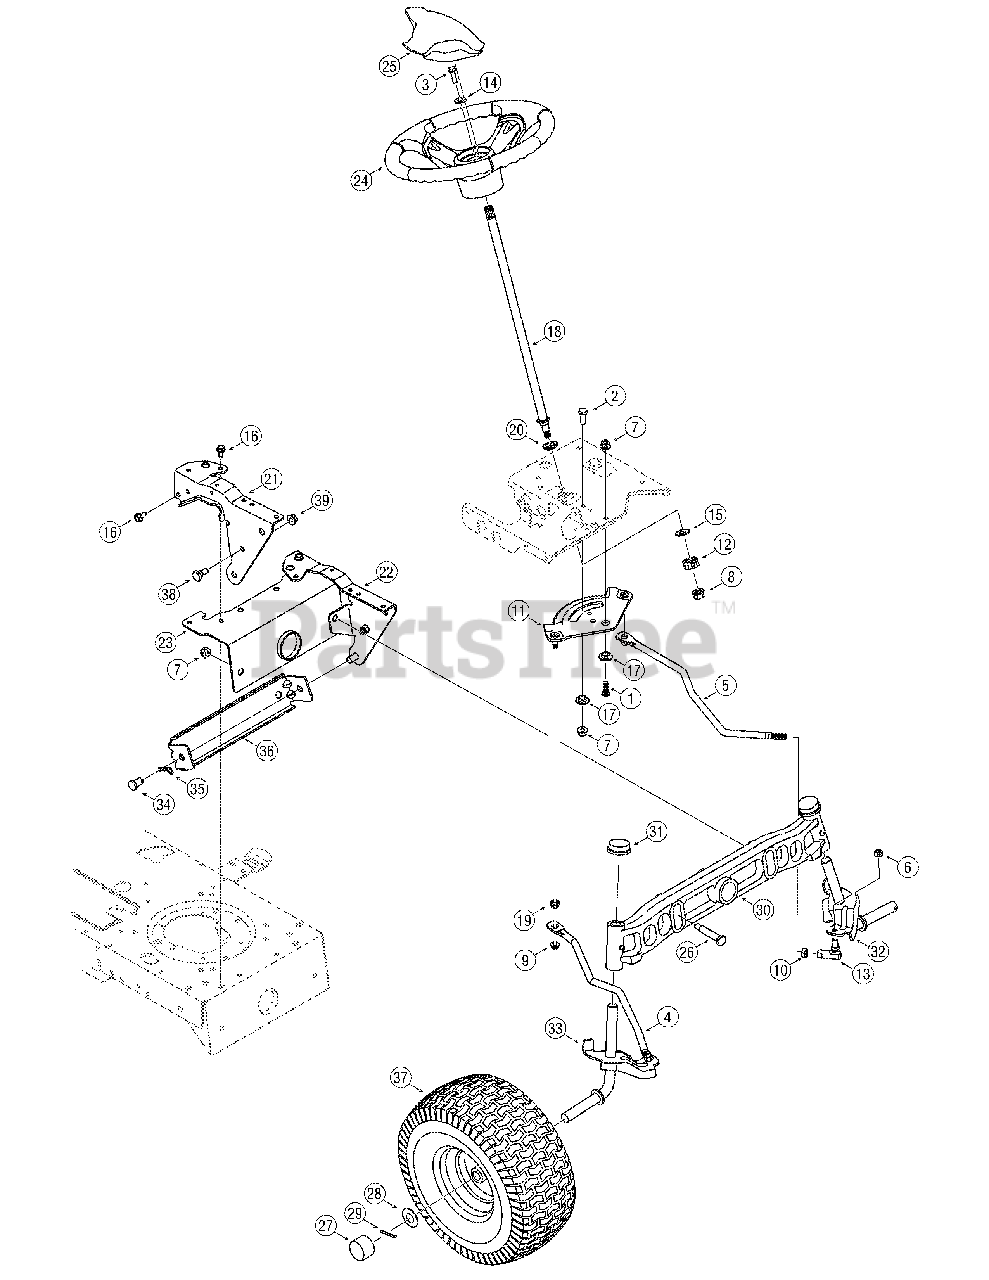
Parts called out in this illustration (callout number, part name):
1	Hex Screw, 3/8-16, 1.00, Gr5
2	Hex Screw, 3/8-16, 1.00, Gr5
3	Hex Screw, 5/16-18, 1.00, Gr5
4	Link, Drag, RH
5	Link, Drag, LH
6	Nut, Hex Lock, 3/8-24
7	Nut, Flange Lock, 3/8-16
8	Nut, Flange Lock, 7/16-20
9	Nut, Flange Lock, 5/16-18, Gr5
10	Nut, Jam, 7/16-20, Gr2
11	Gear, Steering, 11/90 Ratio
12	Gear, Pinion, Steering
13	Ball Joint, 7/16-20, Lock
14	Washer, Flat,.406 x.875 x.105
15	Washer, Flat,.51 x 1.12 x.06
16	Screw, 5/16-18, 0.750
17	Spacer, Shoulder,.38 x 1.00 x.31
18	Shaft, Steering, .625 OD x 24.25
19	Plastic Bushing.380 ID
20	Hex Flange Bearing 5/8 PM
24	Steering Wheel, 13.25
25	Steering Wheel Cover
26	Shoulder Screw,.5 x 2.2, 3/8-16
28	Flat Washer, .781 x 1.589
29	Cotter Pin, 5/32 x 1.25
30	Cast Iron Pivot Bar
32	LH Axle Assembly,.750
33	RH Axle Assembly,.750
34	Pin, Clevis,.50 x.78
35	Cotter Pin, Int., .080 x 1.5625
37	Wheel Assembly Complete
37	Tire Only 16 x 7.5 x 8
37	Rim Only
38	Screw, Shldr,.498 x.340, 3/8-16
39	Flange Lock Nut, 3/8-16
